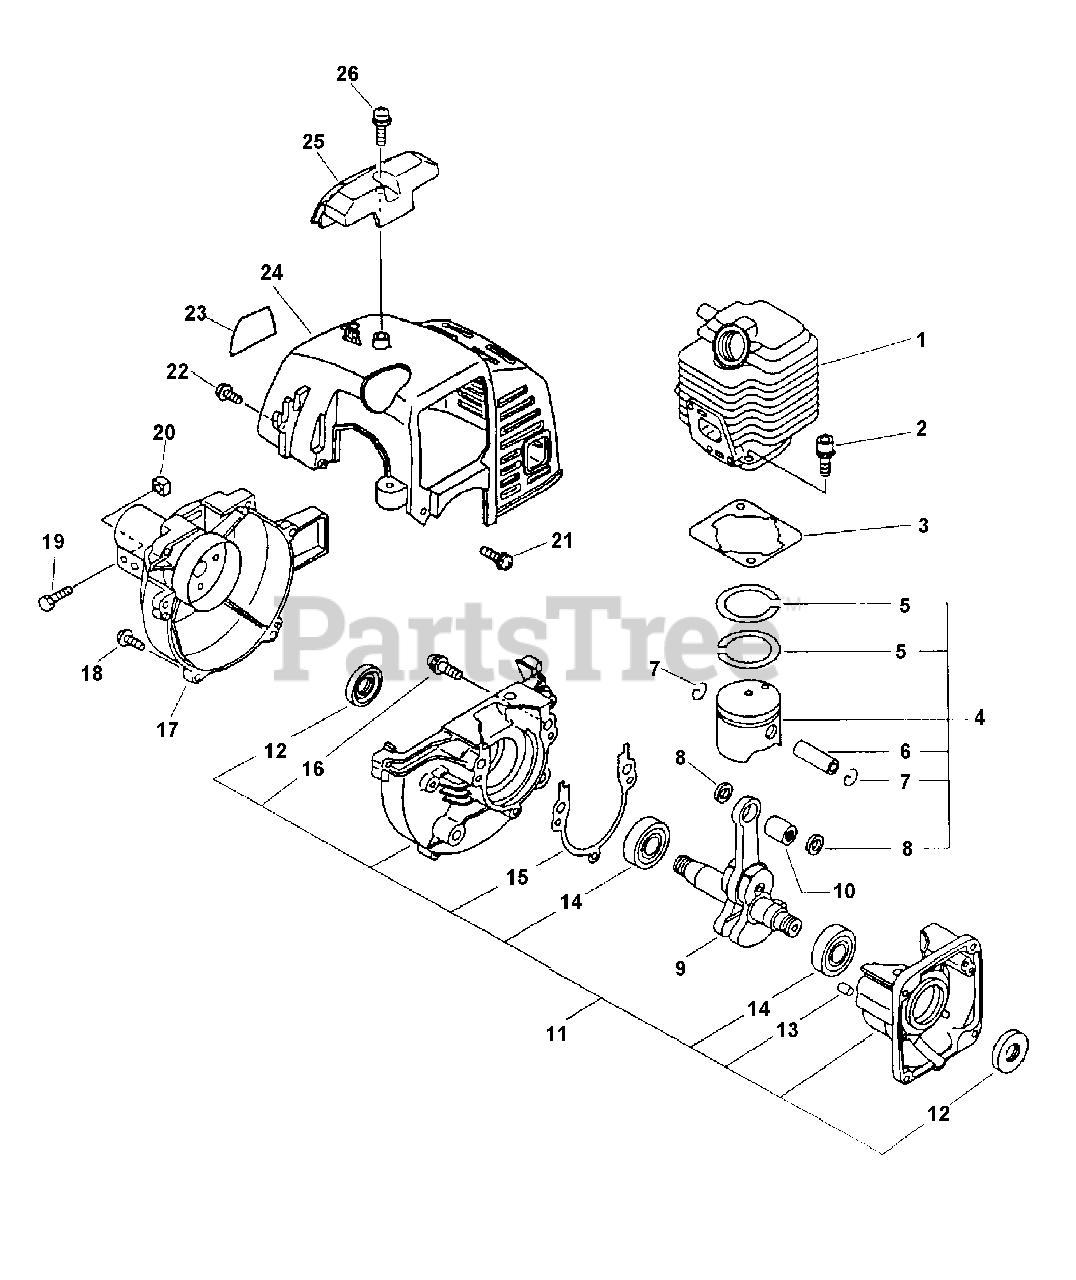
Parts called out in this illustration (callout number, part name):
1	CYLINDER
2	SCREW - 5X22
3	GASKET, CYLINDER
4	PISTON KIT
5	RING, PISTON
6	PIN, PISTON
7	RING, RETAINING
8	SPACER, PISTON
9	CRANKSHAFT ASSY
10	BEARING, NEEDLE
11	CRANKCASE KIT
12	SEAL, OIL
13	PIN - LOCATING
14	BEARING, BALL - 6201
15	GASKET, CRANKCASE
16	SCREW - 5X28
17	FAN CASE ASSY
18	SCREW - 4X18
19	BOLT - 5X28
20	NUT - 5 -- SQUARE
21	SCREW - 4X12 -- TAPPING
22	SCREW - 4X16
23	LABEL - MODEL
24	COVER, ENGINE - GRAY
25	GUARD, TOP - GRAY
26	SCREW - 5X16 -- TAPPING
